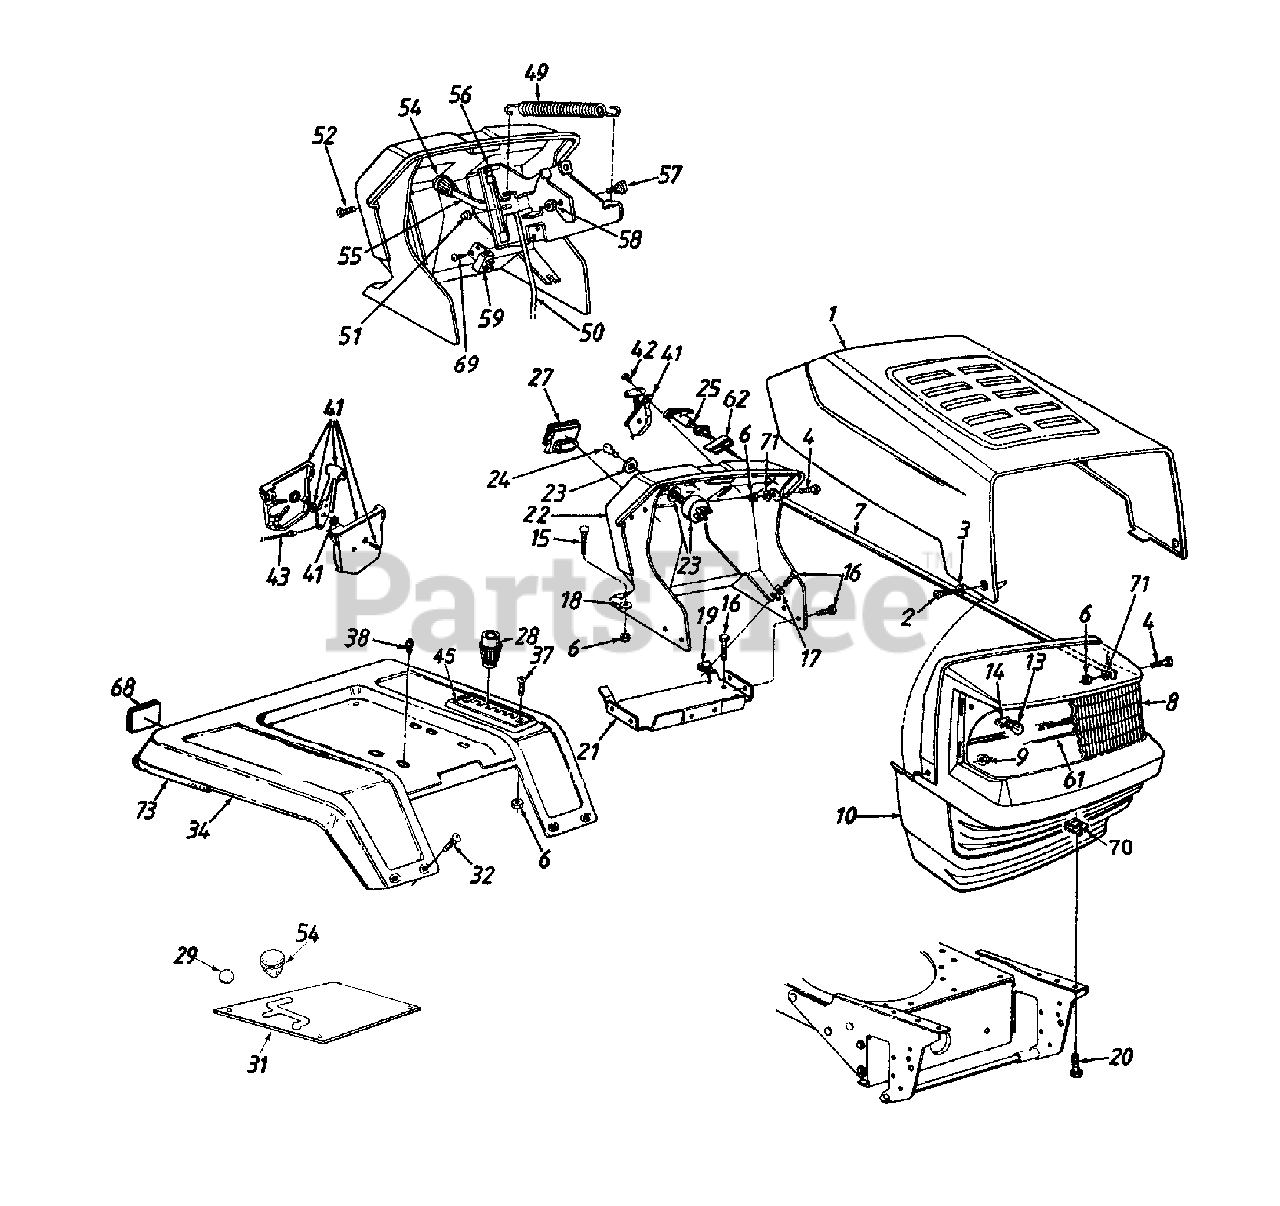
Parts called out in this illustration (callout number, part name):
3	Spr. Wash. .265" I.D. x .562" O.D.
4	Hex Bolt 1/4-20 x .62" Lg.
6	Hex Sems Nut 1/4-20 Thd.
9	Flange L-Nut 1/4-20 Thd.
10	Grille
13	Lamp
14	Socket
15	Carriage Bolt 1/4-20 x 1.0" Lg.
16	Hex AB-Tap Scr. 1/4 x .62" Lg.
17	Fl-Wash. .281" I.D. x .73" O.D.
18	Bolt Retainer 1/4" I.D.
19	Speed Nut 1/4-20 Thd.
20	Hex Bolt 5/16-18 x .75" Lg.
23	Ignition Switch
24	Ignition Key
25	Choke Control
27	Ammeter (Optional)
28	Shift Knob
38	Hex Wash. Hd. AB-Tap Scr. 5/16 x .75" Lg.
41	Throttle Box Ass'y.
42	Truss Mach. AB-Tap Scr. #10 x .5" Lg.
43	Throttle Control Wire 35" Lg.
45	6-Speed Selector Plate (820)
49	Ext. Spring 5.06" Lg.
50	Deck Control Rod
51	Speed Nut 1/4" Rod
52	Torx Mach. Scr. 1/4 x .62" Lg.
54	PTO Knob
55	PTO Lever
58	Hex L-Nut 5/16-18 Thd.
59	Safety Switch
61	Grille Reflector Label
62	Retainer Clip
68	Reflector (Optional)
69	Hex Wash. Hd. B-Tap Scr. 10 x .38" Lg.
70	U-Nut 5/16-18 Thd.
71	Fl-Wash. .28" I.D. x .75" O.D.
73	Trim Strip 81" Lg.
17426A-0638	FENDER-RR - MTD/TROY-BILT RED (0638)
17426A-0648	FENDER-RR - TECH GRAY (0648)
